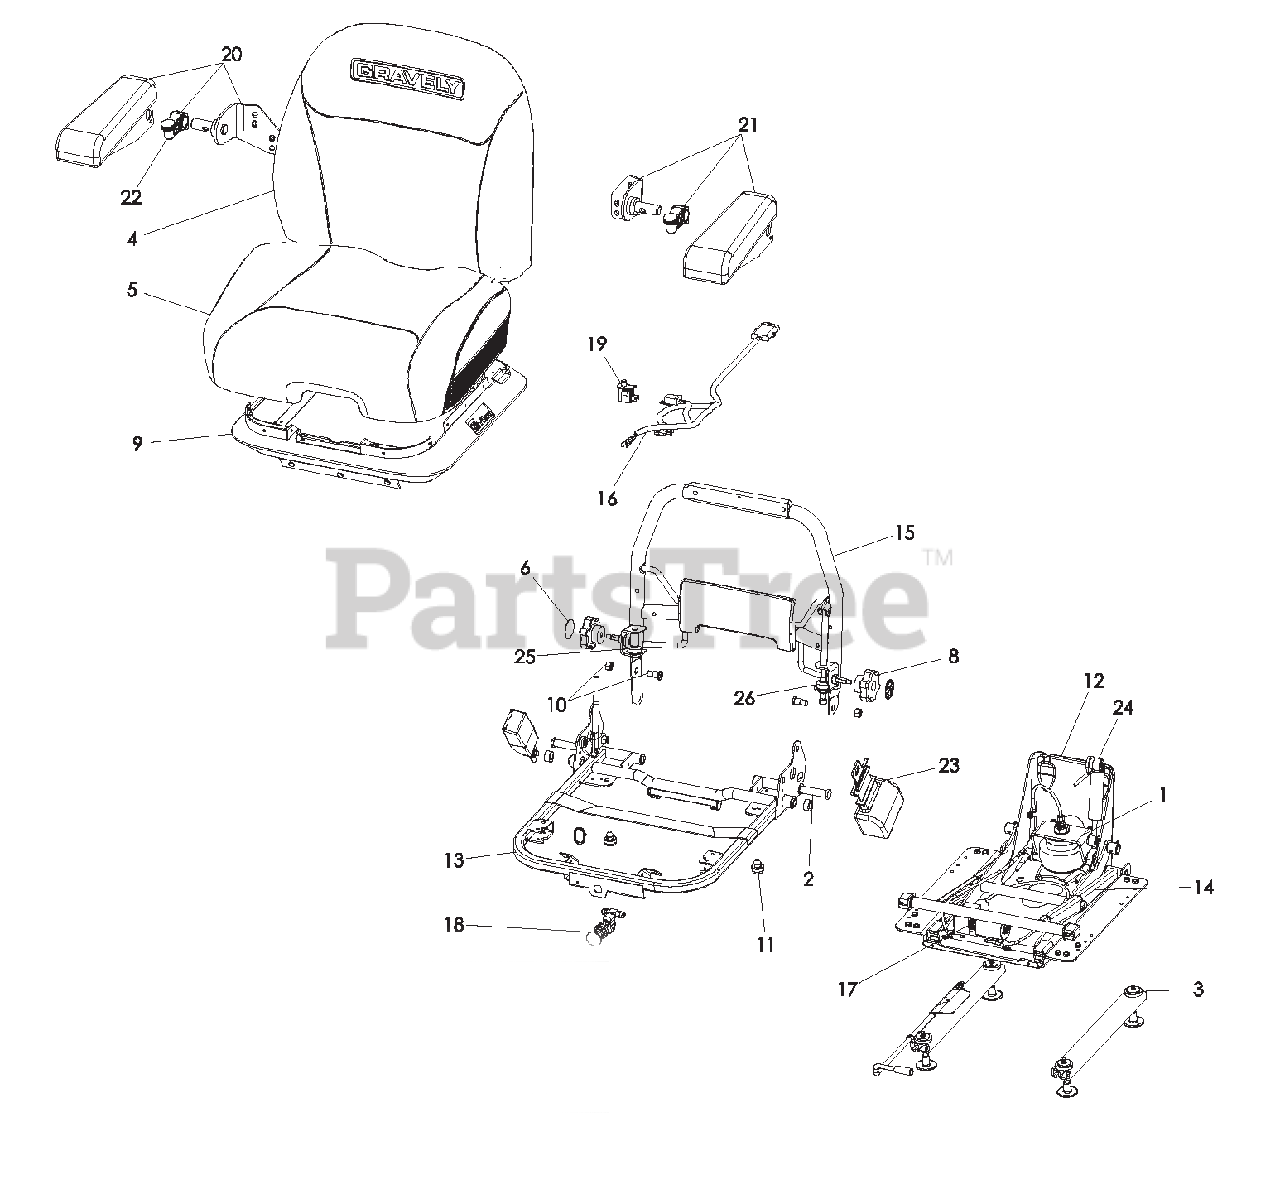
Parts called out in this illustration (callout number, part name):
1	KIT, SPRING & SADDLE
2	KIT, SHAFT/BERAING
3	KIT, SLIDE
4	KIT, BACK CUSHION
5	KIT, SEAT CUSHION
6	KIT, LABEL
7	KIT, BACK PANEL
8	KIT, KNOB
9	KIT, BOOT
10	KIT, PIVOT BOLT
11	KIT, BUMPER
12	KIT, SUSPENSION BASE WELDMENT
13	KIT, SEAT FRAME WELDMENT
14	KIT, LINKAGE ASSEMBLY
15	KIT, BACK FRAME WELDMENT
16	KIT, WIRE HARNESS
17	KIT, COMPRESSOR
18	KIT, AIR VALVE
19	KIT, OPS SWITCH
20	KIT, RH ARMREST ASSEMBLY
21	KIT, LH ARMREST ASSEMBLY
22	KIT, ARMREST STOP
24	KIT, SHOCK ABSORBER
25	KIT, GEAR
26	KIT, GEAR
